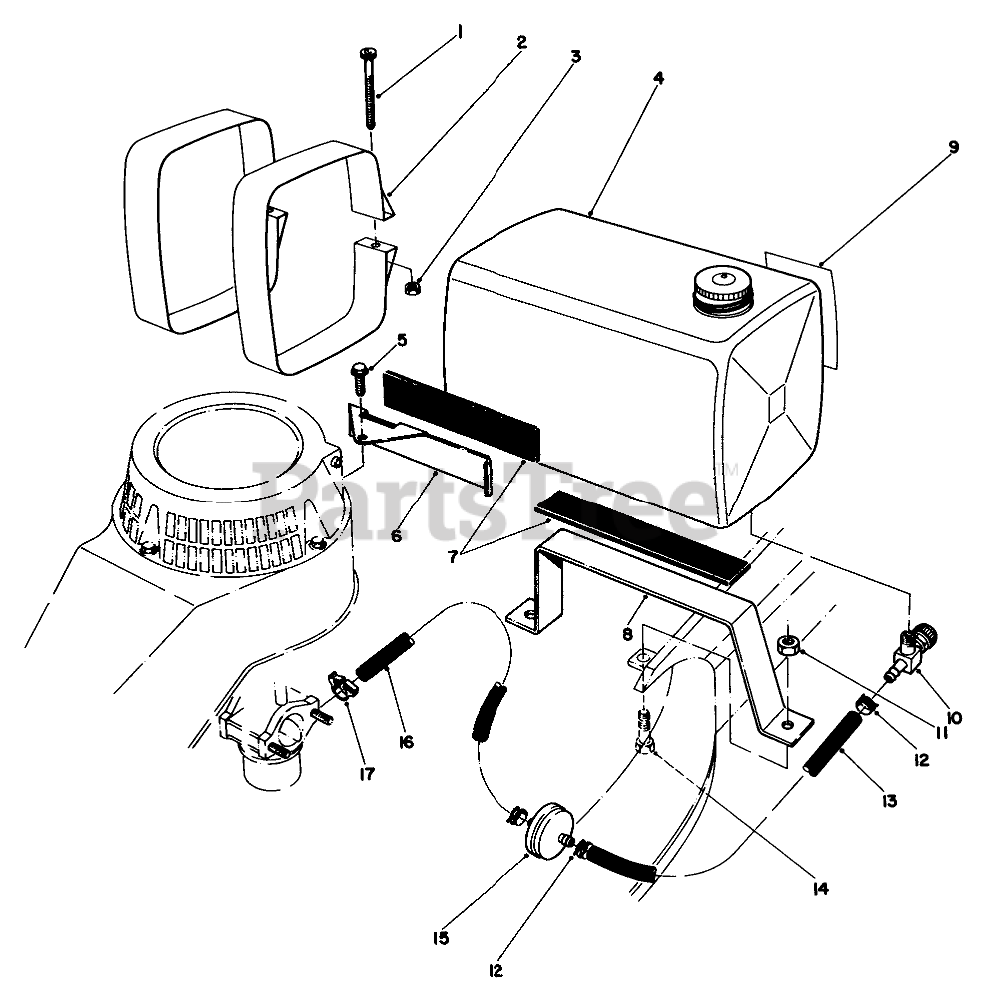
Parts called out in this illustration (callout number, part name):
1	SCREW-HSH
2	TANK MTG STRAP WA
3	NUT-HEX
4	Tank-Gas
5	SCREW-HHF
6	FRT TANK MOUNT
7	ISOLATOR PAD
8	BOTTOM TANK MOUNT
9	FUEL TANK DECAL
10	.125 ID SHUTOFF VALVE
11	NUT-LOCK, CONE
12	FUEL HOSE CLAMP
13	HOSE-FUEL
14	SCREW-HH
15	Nut
16	LINE-GAS
17	FUEL LINE CLAMP
